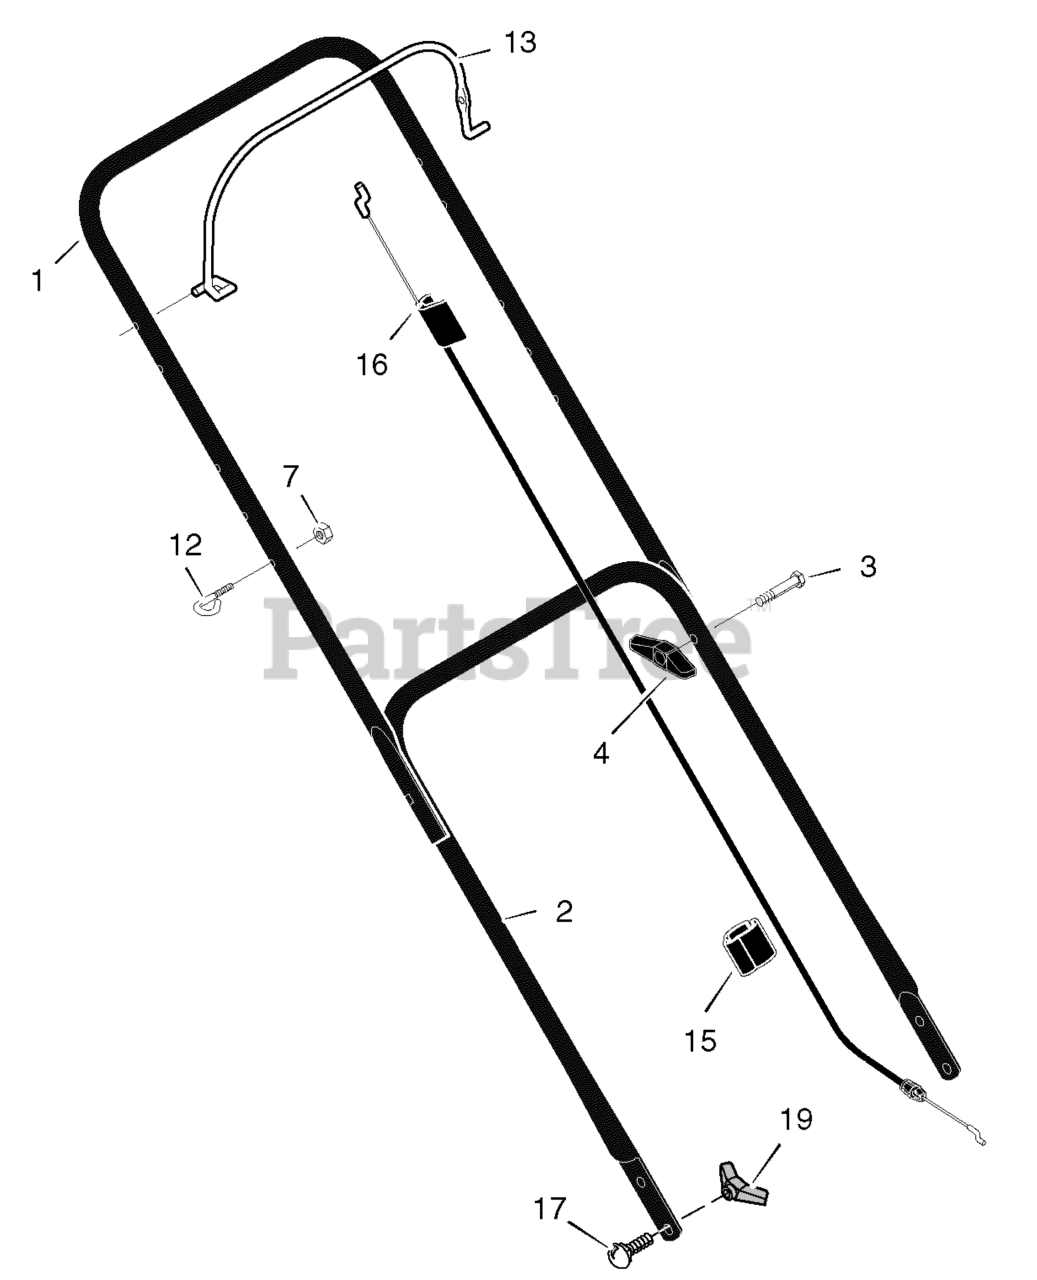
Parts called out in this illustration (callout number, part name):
1	Handle, Upper (Black)
1	Handle, Upper (Gray)
2	Handle, Lower (Black)
2	Handle, Lower (Gray)
4	Knob, Plastic
7	Locknut
12	Guide, Rope
13	Lever, Engine Stop
15	Clip, Cable
16	Engine Stop Cable
17	Bolt, Carriage
19	Knob, Plastic
